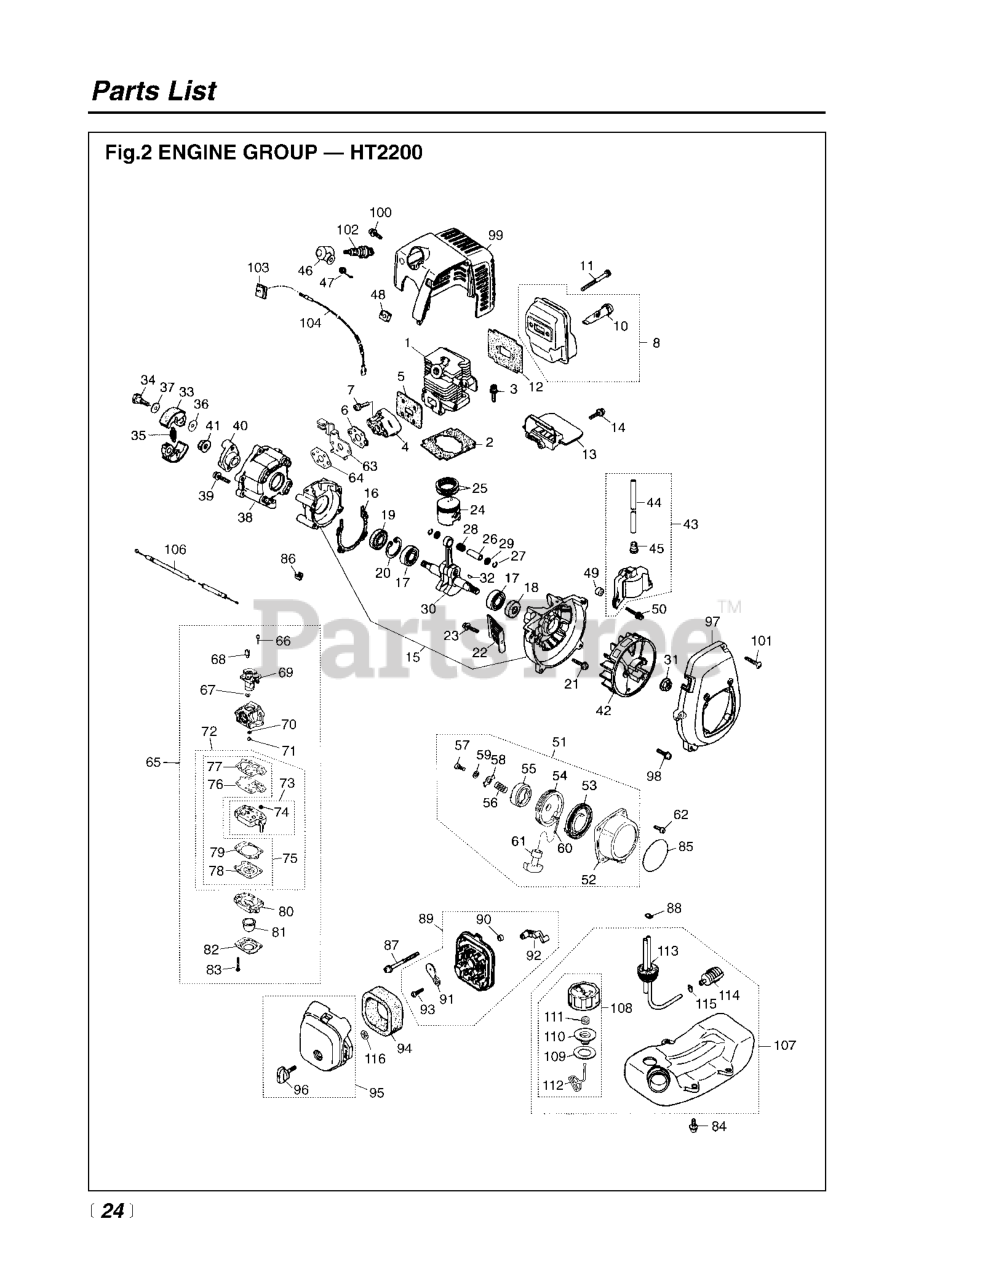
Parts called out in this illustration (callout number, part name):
1	CYLINDER
4	INSULATOR
8	MUFFLER ASSEMBLY
10	ARRESTER
11	BOLT, M5 x 50 (RPLS 125230550)
15	CRANKCASE-C
19	SEAL
25	RING
26	PIN.PISTON
30	CRANKSHAFT (RPLS 560042000)
31	NUT
32	KEY
41	NUT
43	COIL-A
45	CAP
48	GROMMET
49	SPACER
51	RECOIL-A
53	SPRING.SPIRAL
65	CARBURETOR ASSY
67	RING
68	SWIVEL
69	RedMax TBD
72	REBUILD KIT
73	CARBURETOR BODY
74	RedMax TBD
75	GASKET KIT
76	RedMax TBD
77	RedMax TBD
78	RedMax TBD
79	RedMax TBD
82	1OVER
88	CLIP
89	BODY-A
91	PLATE.CHOKE
93	SCREW
95	COVER-A
97	COVER.FAN
107	TANK-A
110	HOLDER-A
113	PIPE COMPLETE
115	CLIP
116	CLIP
